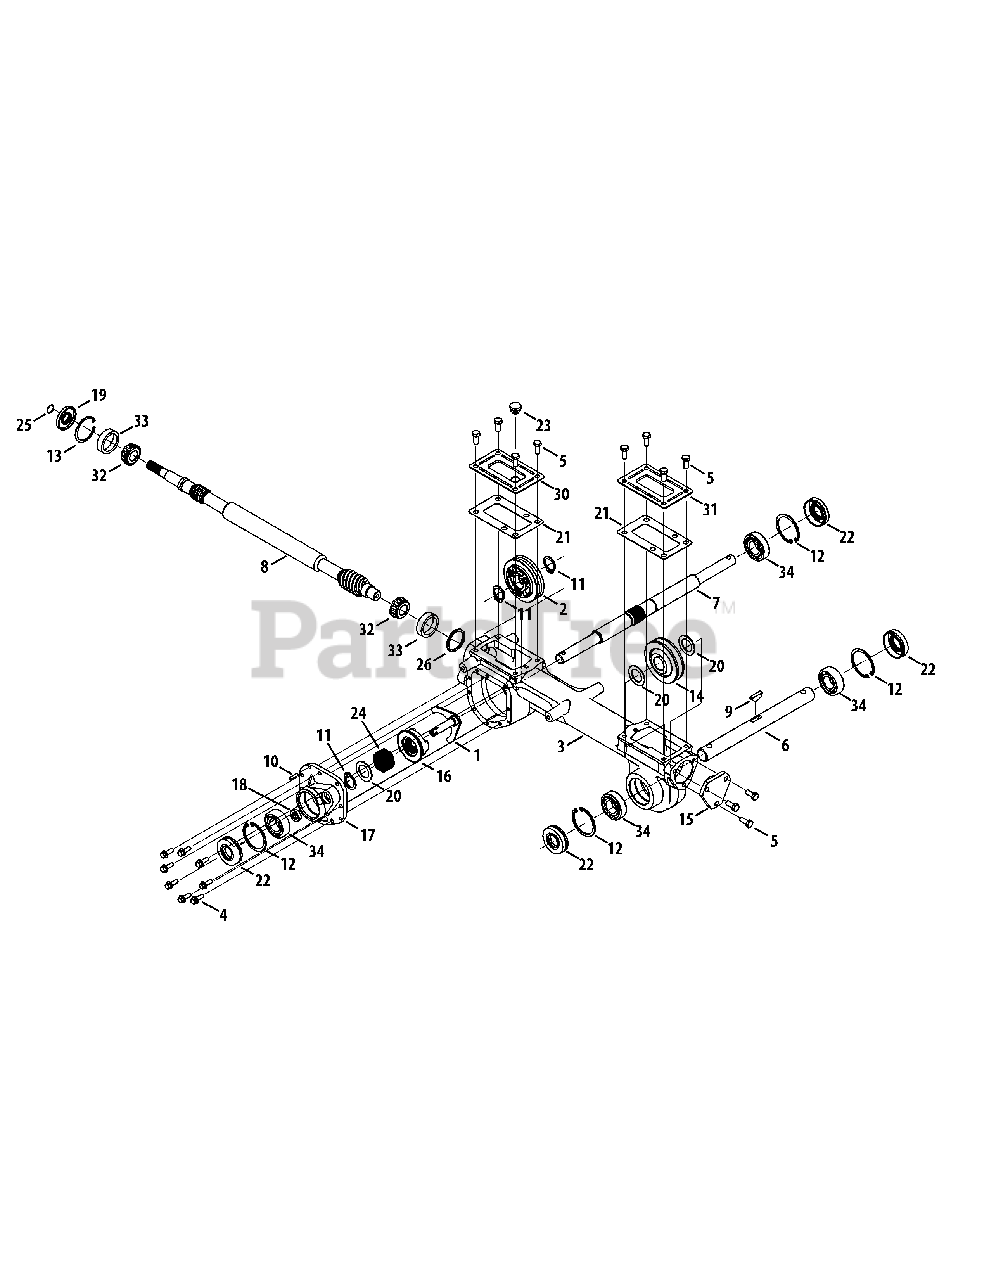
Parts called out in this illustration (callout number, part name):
1	Yoke Wheel Shaft Assembly
2	Worm Gear Assembly
3	Transmission Housing
4	Hex Flange Screw, 1/4-20 x .75
5	Hex Head Screw, 5/16-18 x .75
6	Tiller Shaft
7	Wheel Shaft
8	Front Worm Shaft
9	Key, .25 x 1.062
10	Pin, Dowel, 3/16 x 3/4
11	Snap Ring, 1.00 Shaft Dia.
12	Retainer Ring
13	Retainer Ring
14	Worm Gear, 30T, RH
15	Bearing Cover
16	Disconnect Collar
17	Wheel Cover
19	Oil Seal, .750 SHF x 1.783 BORE
20	Washer, Flat, 1.010 x 1.56 x .060
21	Gear Housing Gasket
22	Oil Seal, 1.00 SHF x 2.00 BORE
23	Rubber Oil Plug
24	Spring, 1.5 x 1.14 x .800
25	Ring, Wire
26	Washer, Flat, 1.50 x 1.75 x .062
26	Washer, Flat, 1.50 x 1.75 x .005
26	Washer, Flat, 1.50 x 1.75 x .03
26	Washer, Flat, 1.50 x 1.75 x .010
30	Tiller Transmission Cover
31	Tiller Transmission Cover
32	Cone Bearing
33	Cup Bearing
34	Ball Bearing, 1 x 52 x 15 x 6205-1
